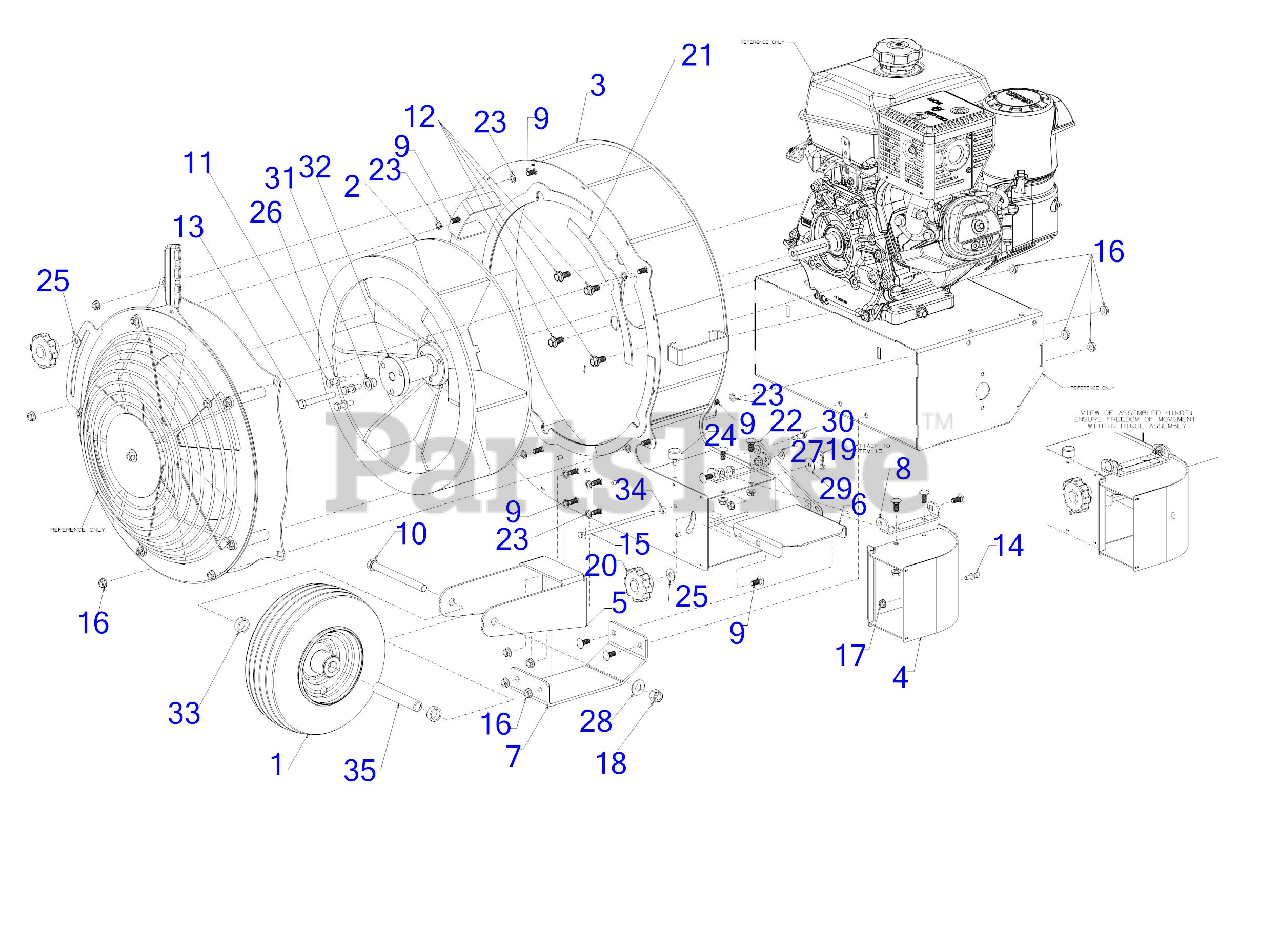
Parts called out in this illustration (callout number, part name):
1	WHEEL ASSEMBLY 11 x 4 x 5
2	IMPELLER ASSEMBLY
9	CARRIAGE BOLT 5/16-18 x .75
10	SCREW 1/2-20 x 5.50 GR5
11	SCREW 5/16-18 x 1.25 GR5
12	BOLT - 3/8-16:.75:GR5:PATCH LOCK
13	SCREW 3/8-24 x 2.75 GR5
14	PIN 1/4-20
15	PIN CLEVIS .25 X 6.50
16	FLANGE NUT
17	LOCK NUT 1/4
18	HEX NUT CENTER
19	BOW TIE COTTER PIN 1/4-5/16
20	KNOB-5/16-18
21	SEAL BLOWER HOUSING
22	CHUTE STRAP
24	BUMPER .62 DIA x .50
25	FLAT WASHER
26	FLAT WASHER
27	FLAT WASHER
28	FLAT WASHER
29	FLAT WASHER
30	SHOULDER SCREW
31	SHOULDER SPACER .875 X .38 X .55
32	BLOWER IMPELLER LOCK FLANGE
33	SPACER .790 ID 1
35	WHEEL SPACER
